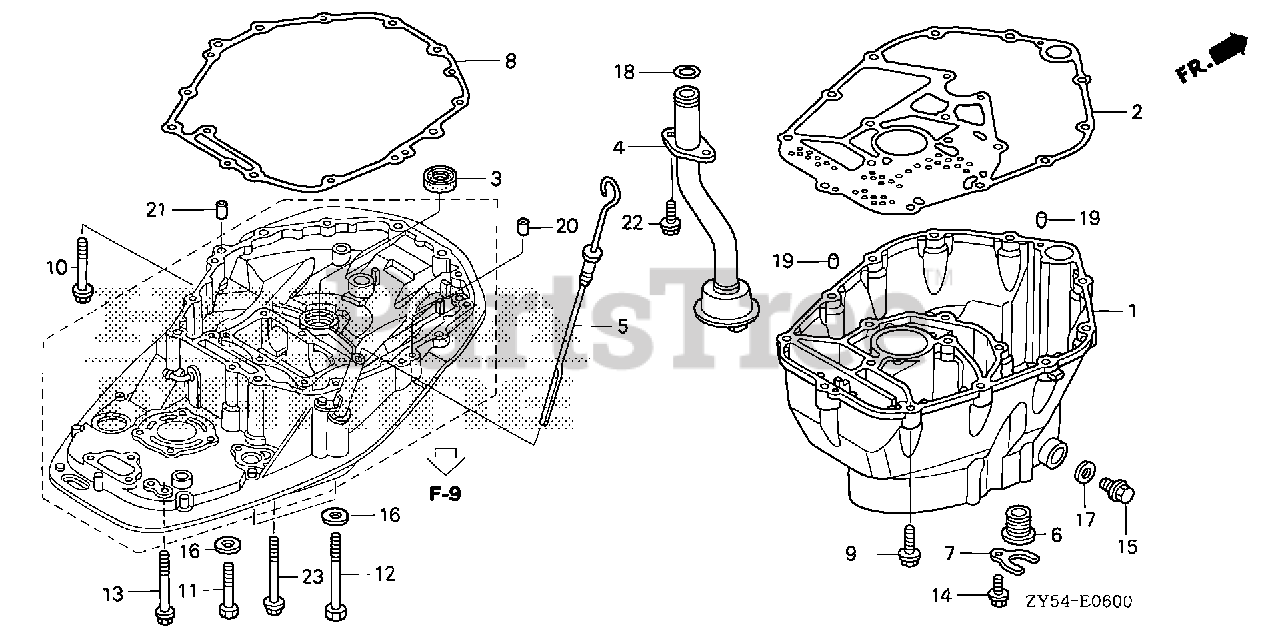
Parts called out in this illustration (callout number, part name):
1	CASE, OIL *NH8* (DARK GRAY)
2	GASKET, OIL PAN
3	RUBBER, OIL PUMP
4	STRAINER, OIL
5	DIPSTICK, OIL
6	GROMMET, WATER TUBE
7	PLATE, WATER TUBE
8	GASKET, MOUNT CASE
9	BOLT, FLANGE (10X40)
10	BOLT, FLANGE (10X80)
11	BOLT, HEX. (12X70)
12	BOLT, HEX. (12X130)
13	BOLT, FLANGE (8X100)
14	BOLT, FLANGE (6X12)
15	BOLT, DRAIN PLUG
16	WASHER, PLAIN (12MM)
17	WASHER, DRAIN PLUG (12MM)
18	O-RING (20.6X2.6)
19	PIN, DOWEL (6X10)
20	PIN, DOWEL (10X16)
21	PIN, DOWEL (14X20)
22	BOLT, FLANGE (6X18)
23	BOLT, FLANGE (10X110)
